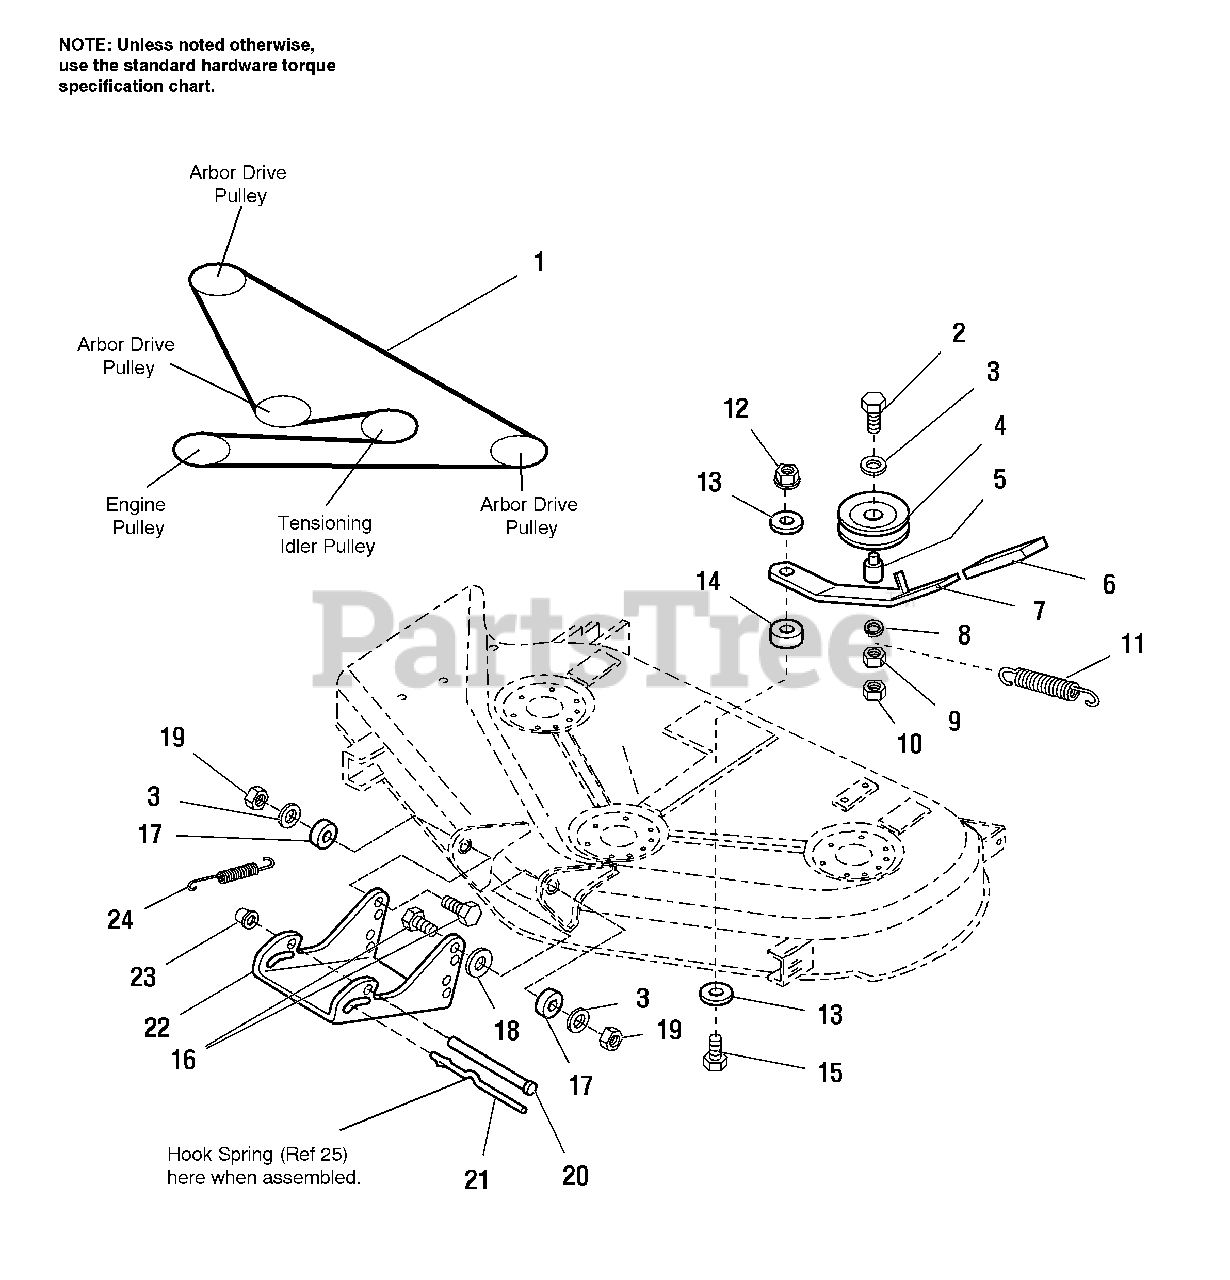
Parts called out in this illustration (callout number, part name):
2	CAPSCREW, Hex Hd, 3/8-16 x 2-1/2
3	WASHER, 3/8
4	PULLEY ASSEMBLY
6	GRIP, Lever
8	LOCKWASHER, Spring, 3/8
9	NUT, Hex, 3/8-16
10	NUT, Hex Flange Whiz Lock, 3/8-16
12	NUT, Hex, Center Lock, 3/8-16
13	WASHER, 3/8
14	SPACER, Idler Arm
15	CAPSCREW, Hex Hd, 3/8-16 x 1-1/4"
16	CAPSCREW, Hex Hd, 3/8-16 x 1-1/2
18	WASHER, 3/8
19	NUT, Hex Nylon Lock, 3/8-16
20	ROD, Mower Hitch
23	NUT, Push, 1/2
24	SPRING
